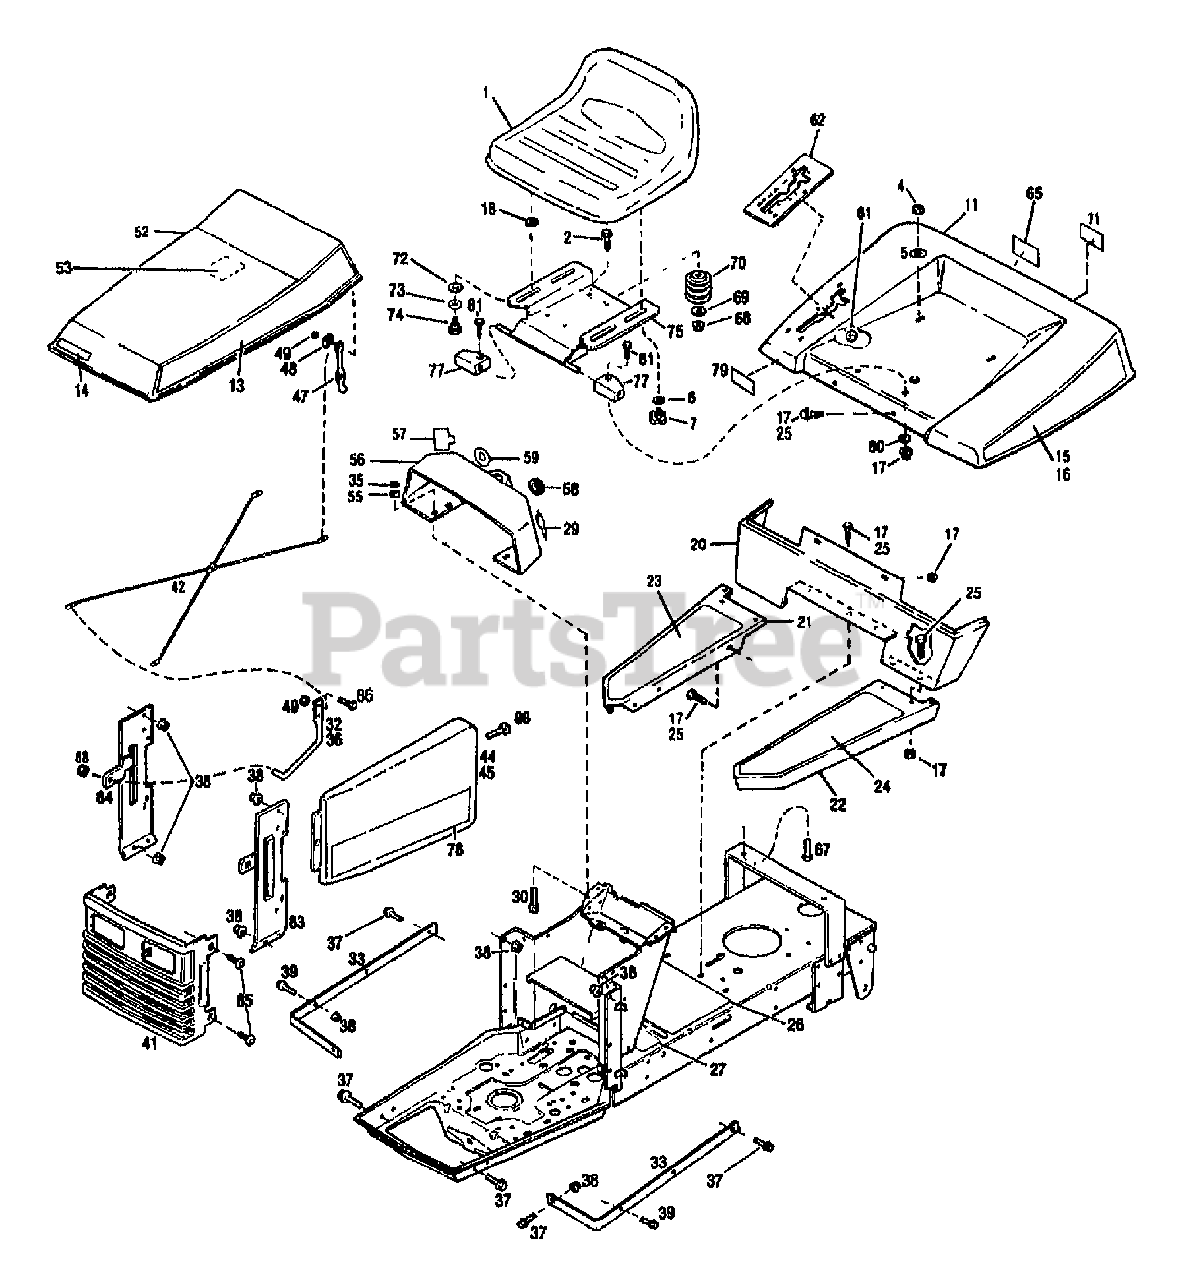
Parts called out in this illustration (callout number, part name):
2	SCR-HFLK 3/8-16X1.00 ZP
4	NUT-TOP/LK 5/16-18 ZP
5	WASHER-1.25X.343X.059
6	WASHER-FLAT 3/8 SAE
11	FENDER-REAR
13	DECAL-LOGO
14	DECAL-LOGO
15	DECAL-FENDER RH
16	DECAL-FENDER LH
17	NUT-HFLK 5/16-18 ZP
18	WASHER-FLAT
20	SUPT-RUNNING BOARD
21	BOARD-RUNNING RH
22	BOARD-RUNNING LH
23	PAD-FOOT RH
24	PAD-FOOT LH
25	SCR-LOCK
26	PAD-FOOT
27	DECAL-INST
29	DECAL-CHOKE
30	SCR-HH 1/4-20X.625 G5 ZP
32	LINK-HINGE RH
33	ASSM-HINGE STRAP
35	NUT-HT/LK 1/4-20
36	LINK-HINGE LH
37	SCR-HH 1/4-20X.625
38	NUT-HF/LK 1/4-20 ZP
39	SCR-HFLK 1/4-20X.50 ZP
42	SUPPORT-HOOD ROD
44	COVER-SIDE LH
45	COVER-SIDE RH
47	LATCH-RUBBER
49	NUT W/LKWASHER 10-24 ZP
52	ASSM-HOOD
53	DECAL-SVC INST
55	WASHER-FLAT 1/4 SAE
56	PANEL-INSTRUCTION
57	DECAL-THROTTLE
59	DECAL-IGNITION
61	NUT-SELF THREADING
62	QUADRANT-SHIFT
65	DECAL-FUEL
67	SCR-CARR 5/16-18X.75
68	NUT-HFLK 3/8-16 ZP
69	WASHER-FLAT 1.25X.406X.179
70	SPRING-COMPRESSION
71	DECAL-LOGO FENDER
72	WASHER-BOW .74X.52X.01
73	WASHER-1.06X.51X.09 NYLON
74	SCR-SHLDR 3/8-16X.25 G5ZP
75	ASSM-SEAT SUPPORT
77	BLOCK-PIVOT
78	DECAL-SIDECVR LH RED
78	DECAL-SIDECVR RH RED
79	DECAL-U.S.A.
80	WASHER-1.5X.343X.104
81	SCR-HH 5/16-18X1.5 G5 ZP
83	ASSM-SUPPORT LH
84	ASSM-SUPPORT RH
86	SCR-HHS 10-24X.625 ZP
88	NUT-SPECIAL
